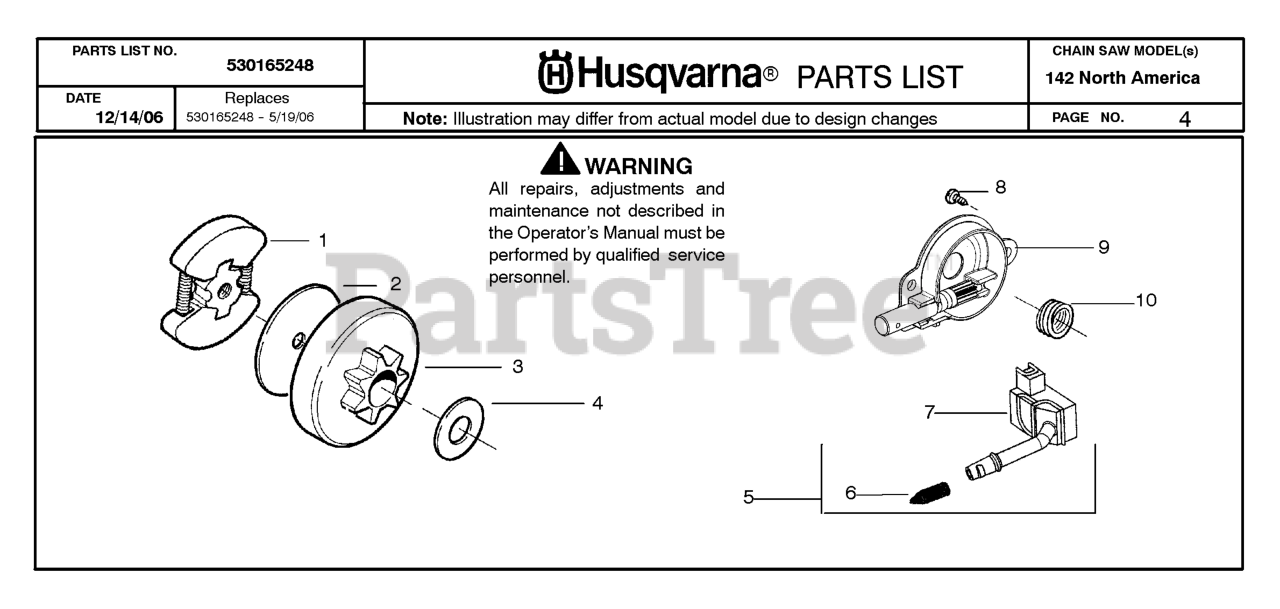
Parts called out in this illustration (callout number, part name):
1	CLUTCH ASSEMBLY
2	FRICTION DISC,CLUTCH 36/41
3	CLUTCH DRUM ASSY
4	THRUST WASHER
5	OIL PICKUP
6	SCREEN/FILTER
9	OILER ASS'Y 36/41
10	OILER GEAR 36/41
